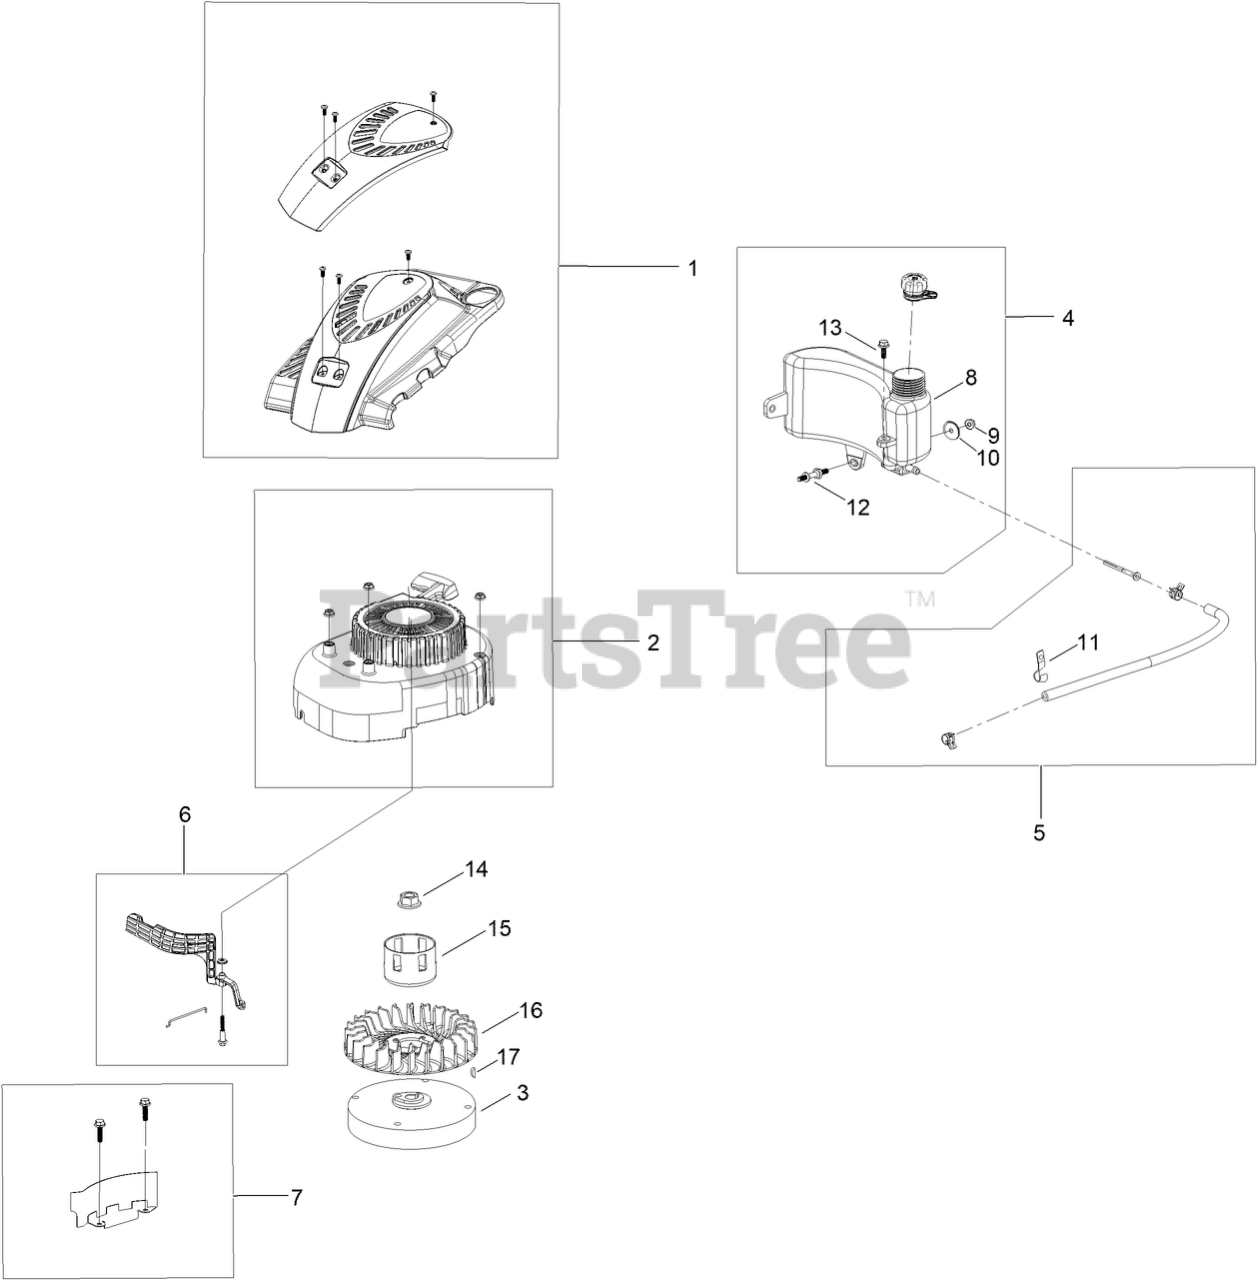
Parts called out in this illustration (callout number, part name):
1	SHROUD ASM
2	RECOIL AND BLOWER SHROUD KIT
3	FLYWHEEL
4	CAP-FUEL
5	FUEL LINE KIT
6	AIR VANE KIT
7	FLYWHEEL SHIELD KIT
8	TANK-FUEL
9	NUT-FLANGE
10	WASHER-FLAT
11	CLIP-HARNESS, WIRE
12	BOLT-STUD
13	BOLT-FLANGE
14	NUT-FLANGE
15	CUP-STARTER
17	KEY-WOODRUFF
